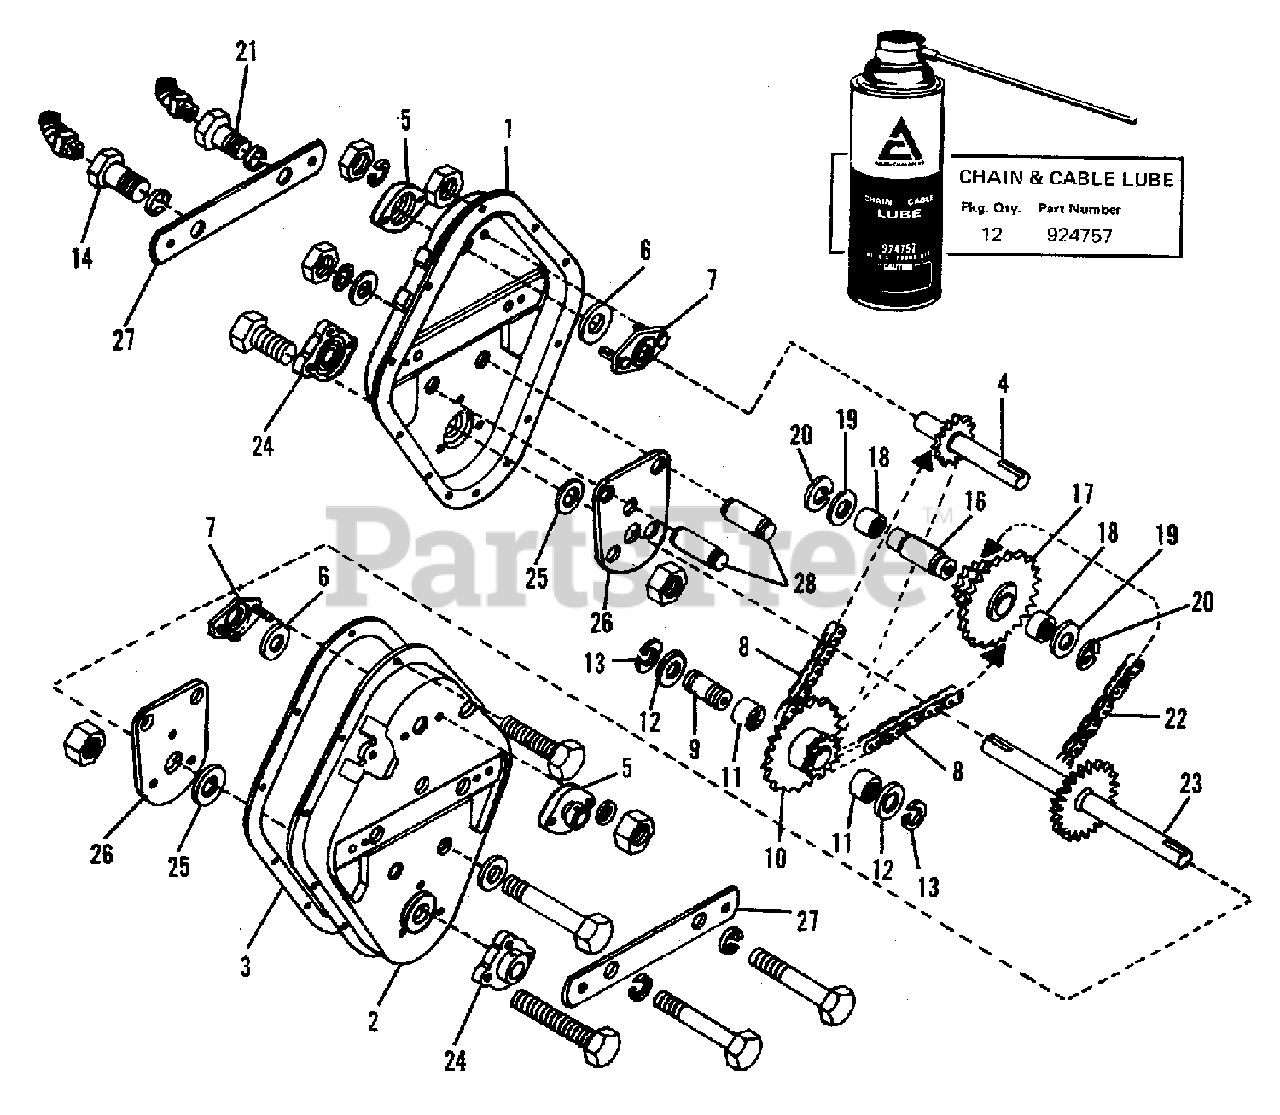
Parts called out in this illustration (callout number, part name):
1	CASE ASSEMBLY, R.H., Half
2	CASE ASSEMBLY, L.H., Half
2	CAPSCREW, 5/16NC x 5/8
2	LOCCKNUT, 5/16NC
2	CAPSCREW, Hexagon, 1/2NC x 4
2	WASHER, Plain, 1/2
2	NUT, 1/2NC, Lock
4	SHAFT ASSEMBLY, Pulley
7	PLATE ASSEMBLY, Upper Bearing
7	WASHER, Lock, 5/16
7	NUT, 5/16NC
9	SPACER, Intermediate
10	SPROCKET ASSEMBLY
11	BEARING, Roller
13	RING, Retaining
14	BOLT, (R.H. Side)
14	FITTING, Grease
16	SPACER, Intermediate
17	SPROCKET ASSEMBLY
18	BEARING, Roller
20	RING, Retaining
21	BOLT (R.H. Side)
21	FITTING, Grease
23	SHAFT ASSEMBLY, Tine
24	SCREW, Thread Forming, 3/8NC X 1-1/2
24	LOCKNUT, Jam, Hexagon, 3/8NC
26	PLATE, Reinforcing
27	BAR, Side, 3/16 x 2 x 13-1/16
27	CAPSCREW, (L.H. Side) 1/2NC x 1-1/4
27	WASHER, Lock, 1/2
28	SPACER, 1 x 7/32 x 3-1/32
